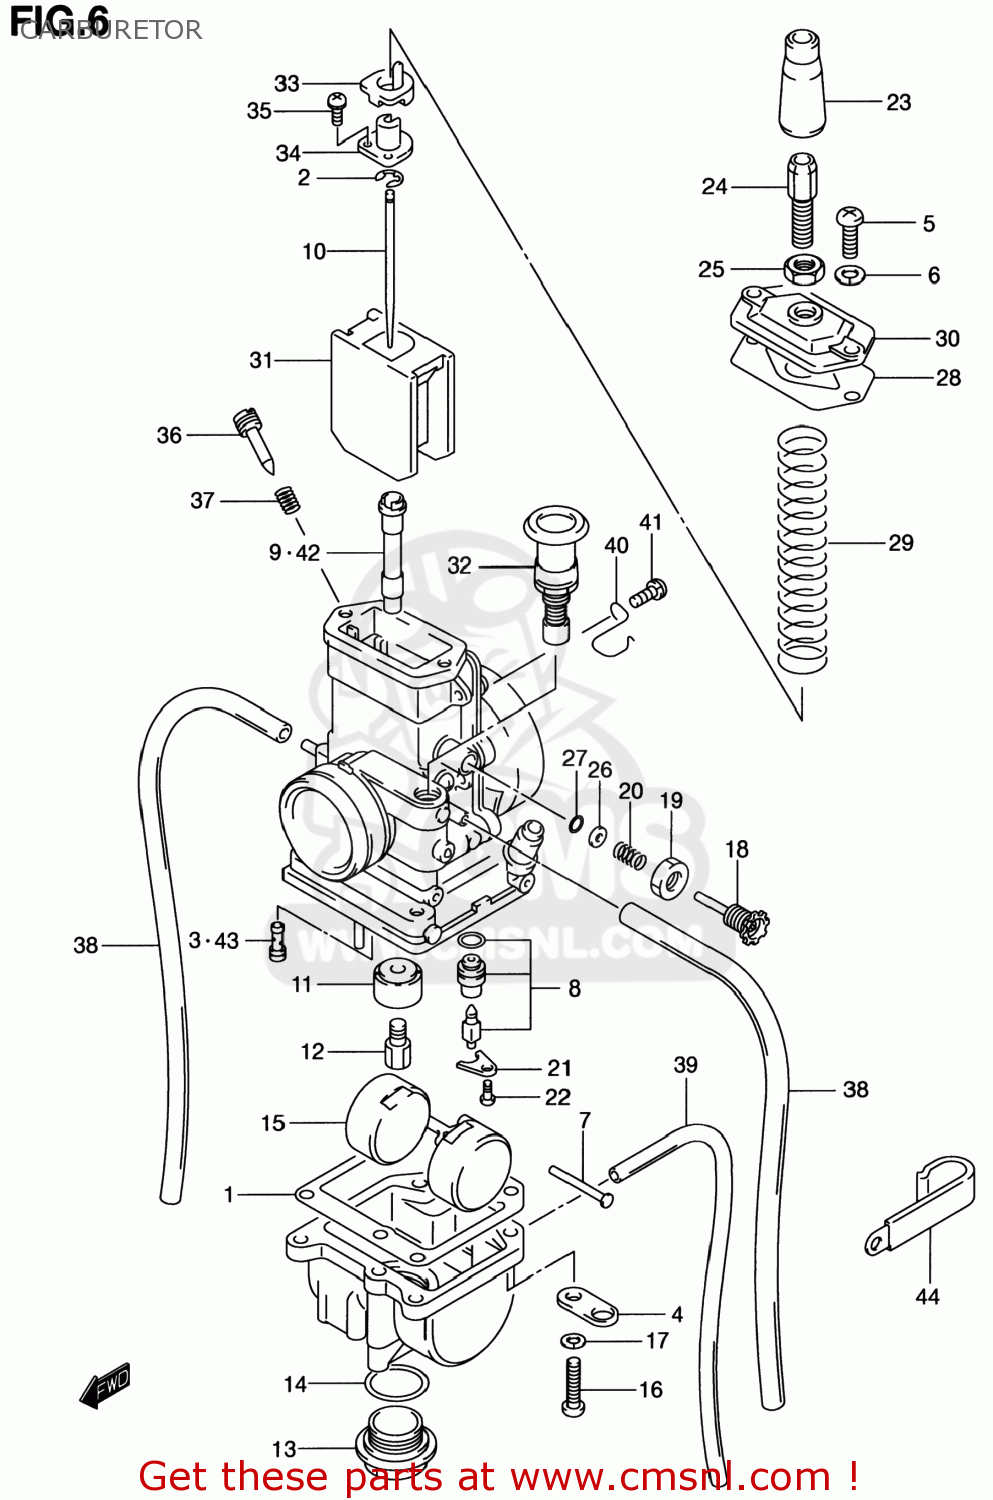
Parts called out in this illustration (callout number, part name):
1	GASKET,FLOAT CAHMBER (NAS)
2	CLIP
3	JET,PILOT(30)
4	PLATE,CARBURETOR
5	SCREW
6	WASHER,LOCK
7	PIN,FLOAT
8	VALVE ASSY,NEEDLE
9	JET,NEEDLE(P-4)
10	NEEDLE,JET(5DP39-4)
11	RING
12	JET,MAIN(210)
13	PLUG
14	O RING
15	FLOAT
16	SCREW
17	WASHER,LOCK
18	ADJUSTER,THROTTLE STOP
19	NUT
20	SPRING
21	PLATE
22	SCREW
23	CAP,CABLE ADJUSTER
24	ADJUSTER,CABLE
25	NUT
26	WASHER
27	O RING
28	GASKET,CARBURETOR TOP (NAS)
29	SPRING
30	CAP,CARBURETOR TOP
31	VALVE,THROTTLE
32	PLUNGER ASSY,STARTER
33	RING
34	JOINT
35	SCREW
36	SCREW,AIR
37	SPRING
38	HOSE(3.5X6.5X600)
39	HOSE(3X5X600)
40	CLIP
41	SCREW
42	JET,NEEDLE,P-2
43	JET,PILOT(25)
44	CLAMP
